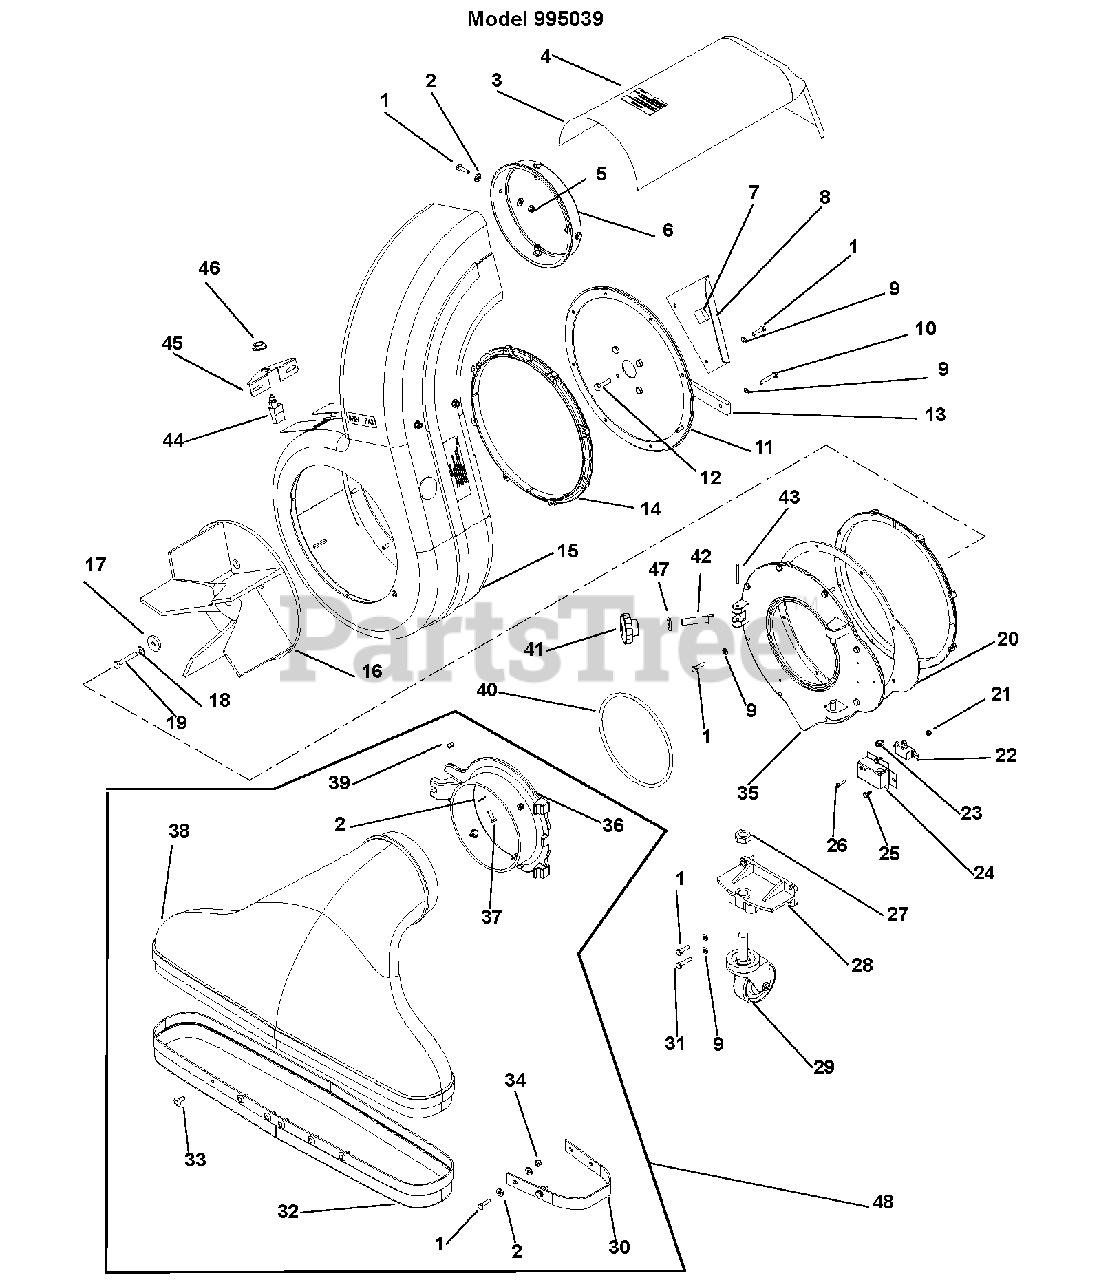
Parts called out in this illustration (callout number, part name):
1	28
2	40
5	2
9	20
10	9
25	3
31	2
34	2
37	4
39	12
47	1
